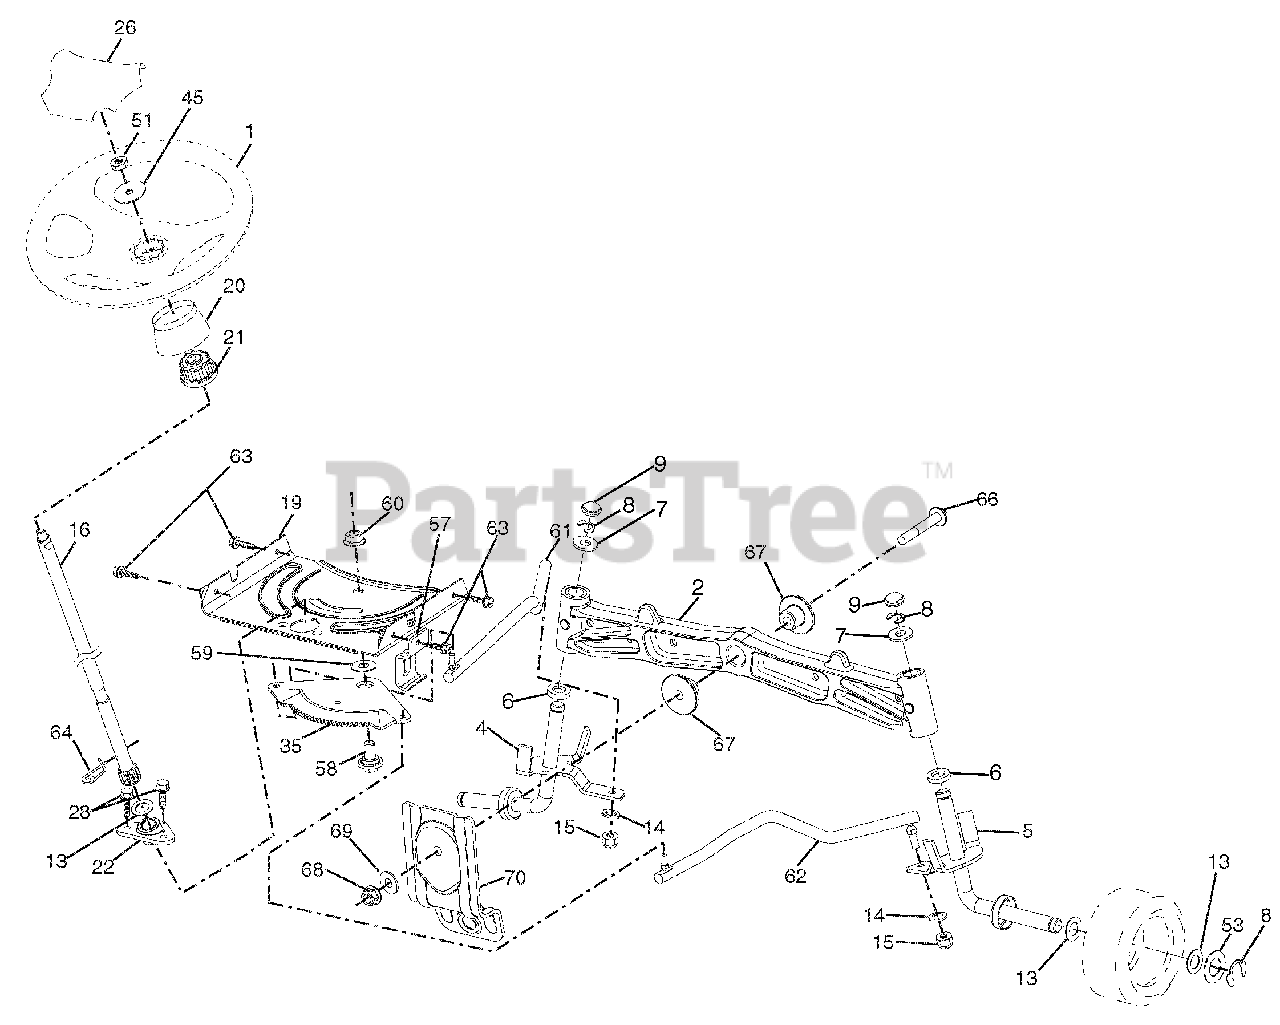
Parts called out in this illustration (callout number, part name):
1	WHEEL STEERING
2	AXLE.CAST IRON
4	SPINDLE.WELDED.LH.15"TEX
5	SPINDLE.WELDED.RH.15"TEX
6	WAHSER THRUST .75 X 1.230
7	WASHER.25/32 X 1-5/8 X 16GA.
8	RING.KLIP.#T5304-75
9	CAP.SPINDLE.FR.TOP.BLK.
13	WASHER.25/32 X 1 1/4 X 16 GA.
14	Washer, Lock 3/8
15	NUT.CROWNLOCK.3/8-24
16	SHAFT.STEER.3/4 TEX.NON-PLATED
19	PLATE.STEER.DDL.NLT/NGT
20	BOOT.STEERING.
21	ADAPTER.WHEEL.STRG..760
22	STEERING SUPT. LOWER
26	CAP WHEEL STEERING BLACK
28	SCREW.HEXWSH THDR3/8-16X3/4.BL
35	GEAR SECTOR.PLATE.DDL.NLT/NGT
45	WASHER.11/32ID X2 3/8OD X 12GA
51	NUT.HEX.JAM.TOPLOCK.1/2-20 UNF
53	WASHER.HARDEN..793 X 1.637X060
57	BRACKET.UPSTOP.GT/LT.TEX
58	BOLT.SHOULDER.SECTOR.PIVOT.CFM
59	WASHER.THRUST.SECTOR.STEER.NLT
60	NUT.FLANGE LOCK.5/8-11
61	DRAGLINK.LH.BALLSTUD.DDL.
62	DRAGLINK.RH.BALLSTUD.DDL
63	SCREW.5/16-18X3/4.SMGML.TAP/BL
64	RETAINER.CLIP.SPRING.STEERING
66	BOLT.HEX.FGHD.7/16-14 X 3.SERR
67	BUSHING.PM.FRONT AXLE
68	NUT.LOCK.FLANGE.7/16-14.GR5
69	WASHER.1.5 X .505 X .118
70	BRACKET.DECK.SUSPENSION.FRONT
